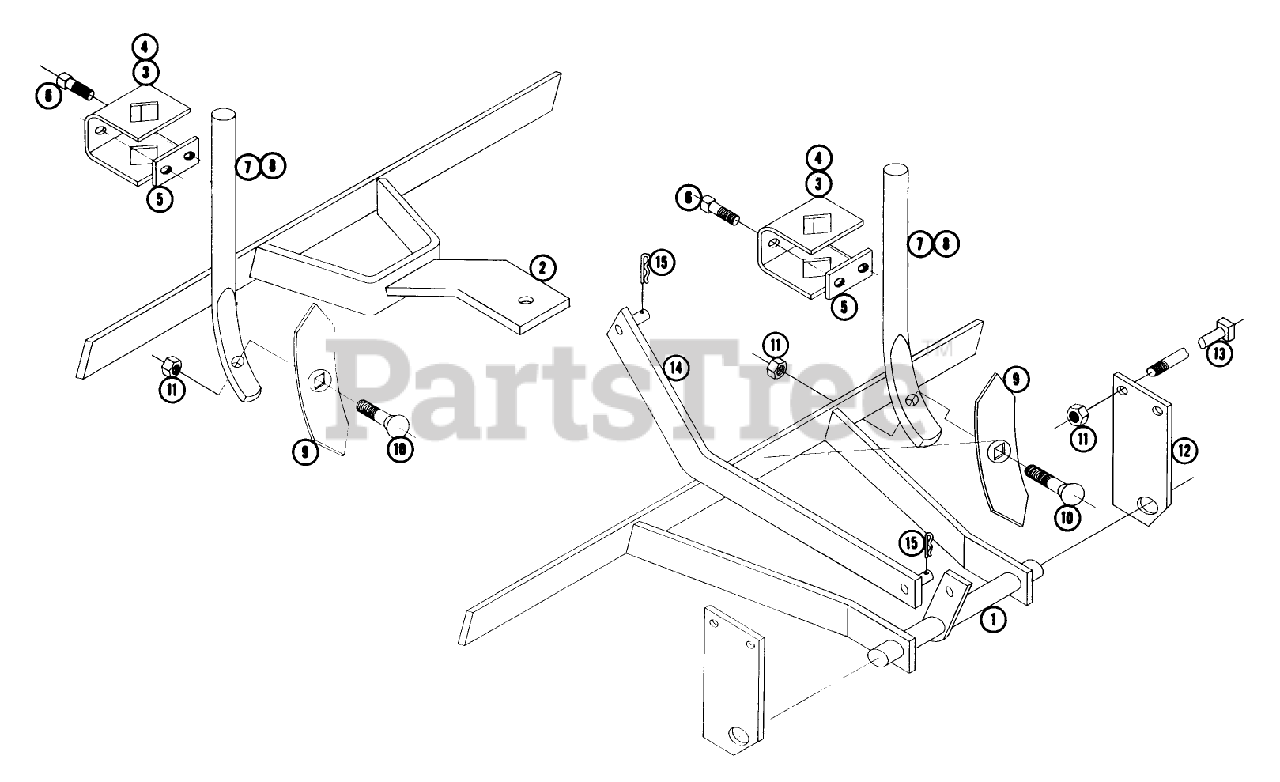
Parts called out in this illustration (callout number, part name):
1	Ass-y. Frame-Front
2	Rear Frame W/A
6	Set Screw, 3/8-16 x 1-1/4
7	Ass-y. Standard Shovel
10	Plowbolt 3/8-16 x 1-1/2
12	Plate-Mounting
13	Bolt 3/8-16 x 1
14	Ass-y. Lift Arm
15	Hairpin
